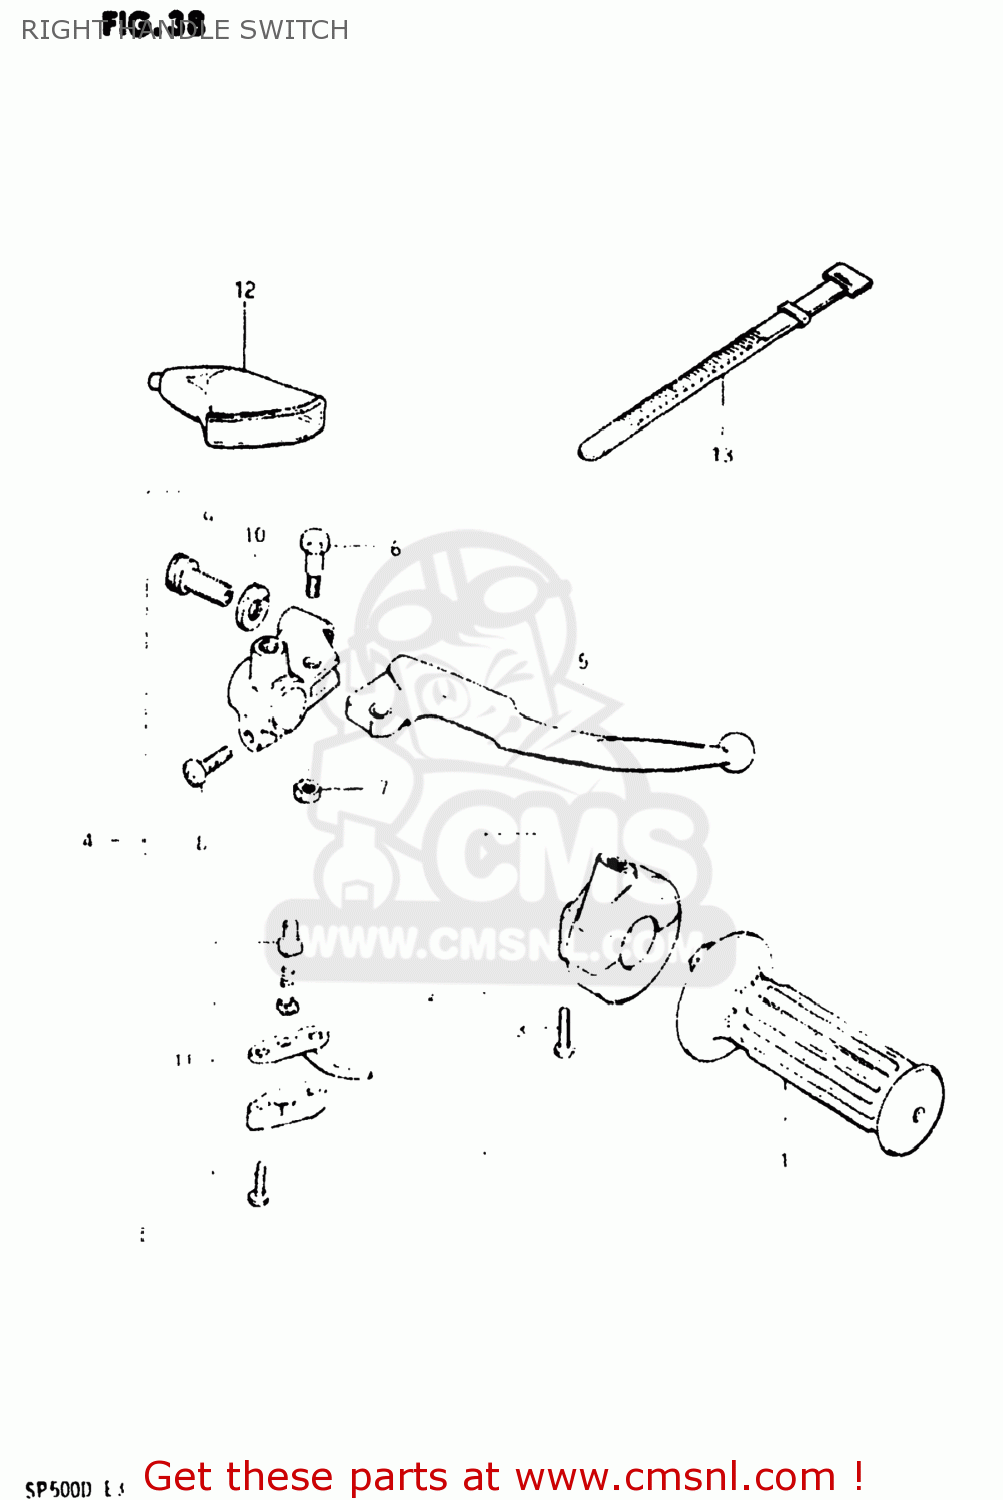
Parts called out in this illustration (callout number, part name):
1	GRIP,THROTTLE
2	CASE ASSY,THROTTLE
3	SCREW 5X20
4	LEVER ASSEMBLY,BRAKE
5	LEVER,BRAKE
6	BOLT,LEVER
7	NUT 6MM
8	SCREW
9	ADJUSTER,CABLE
10	NUT,CABLE ADJUSTER
11	SWITCH ASSEMBLY
12	DUST SEAL,BRAKE/CLUTCH
13	CLAMP
